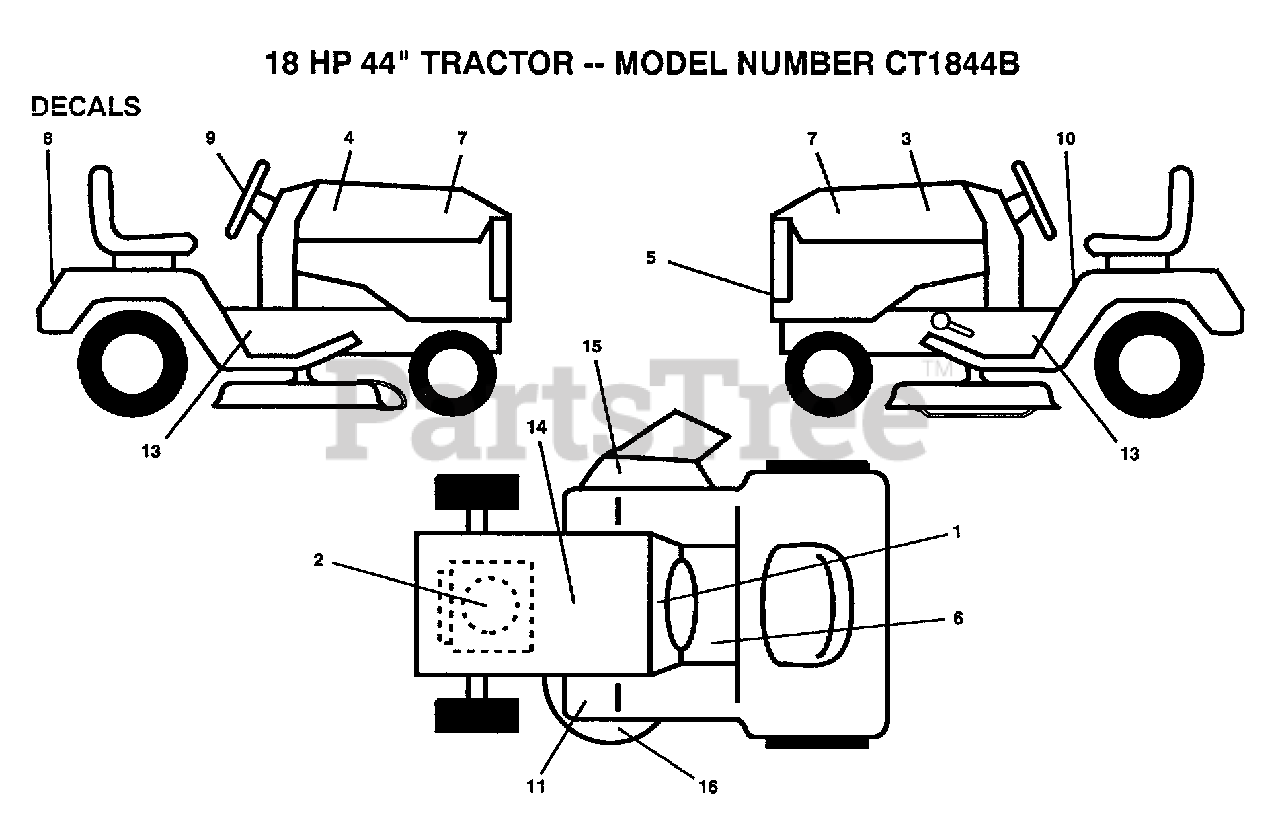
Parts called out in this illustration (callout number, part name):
2	DECAL.ENG.272559
7	DECAL PANEL T
8	"DECAL,FENDER"
10	DECAL CAUTION
11	DECAL T
14	DECAL
15	DECAL WARING
16	DECAL YT
